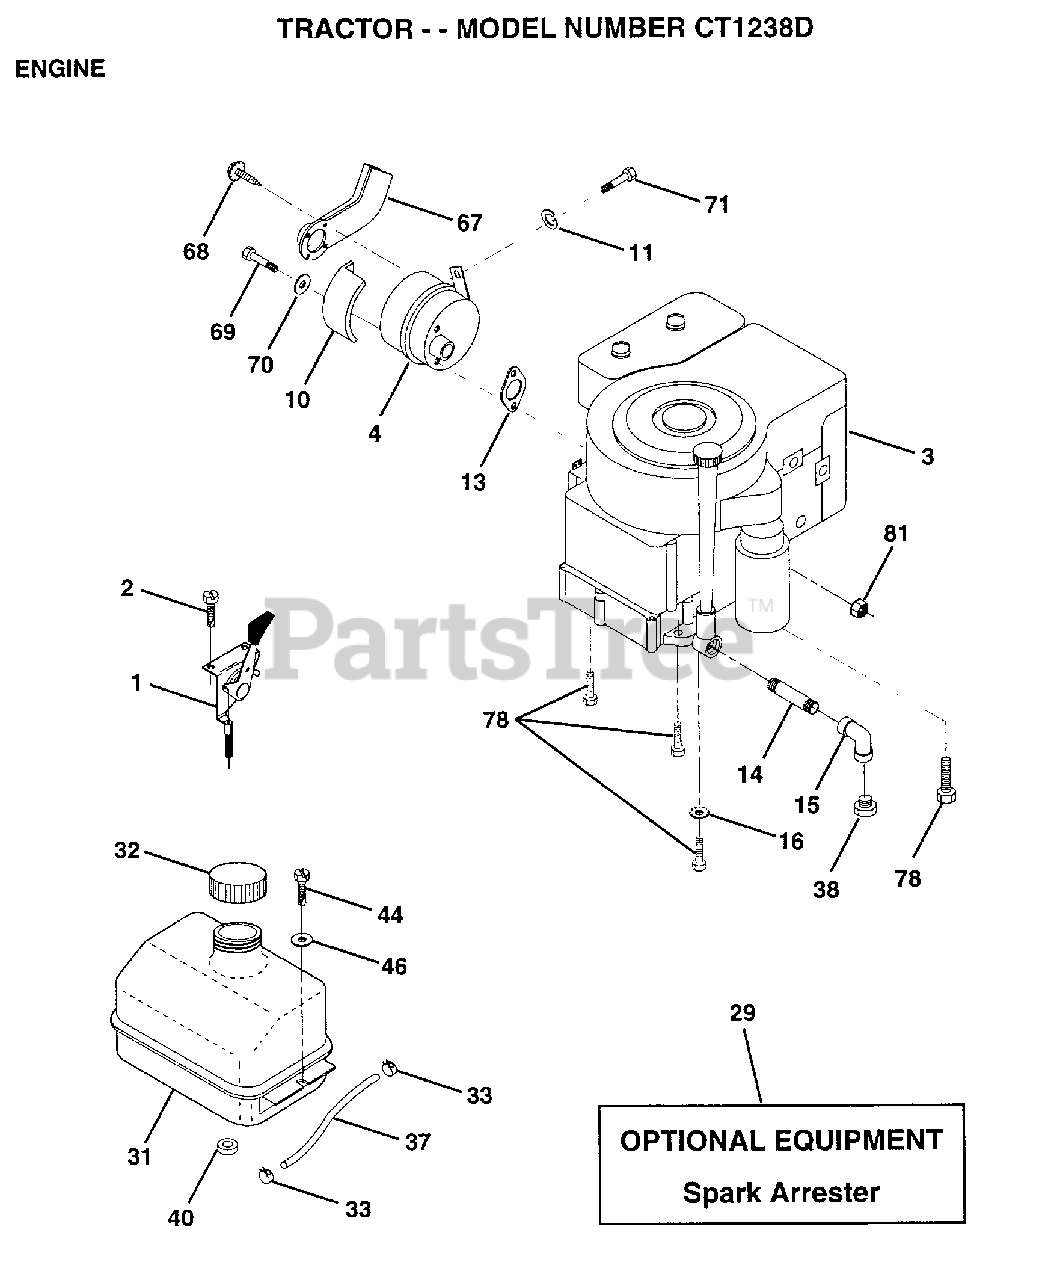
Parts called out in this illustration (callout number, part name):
1	THROTTLE CONTROL
2	SCREW LT
3	ENG B&S 10-12.5HP PWRBLT DC
4	MUFFLER LTV
10	SHIELD HEAT LTV
11	LOCKWASHER
13	GASKET ENG 1 313 LD TIN PLATED
14	PIPE NIPPLE
15	ELBOW
16	LOCKWASHER
31	TANK.FUEL.LT.
32	CAP ASM FUEL
33	HOSE CLAMP
37	LINE FUEL
44	SCREW HEX CRT
46	WASHER
67	DEFLECTOR MUFFLER
69	"BOLT,HEX"
70	WASHER T
71	BOLT HXHD FIN
78	SCREW
81	NUT
